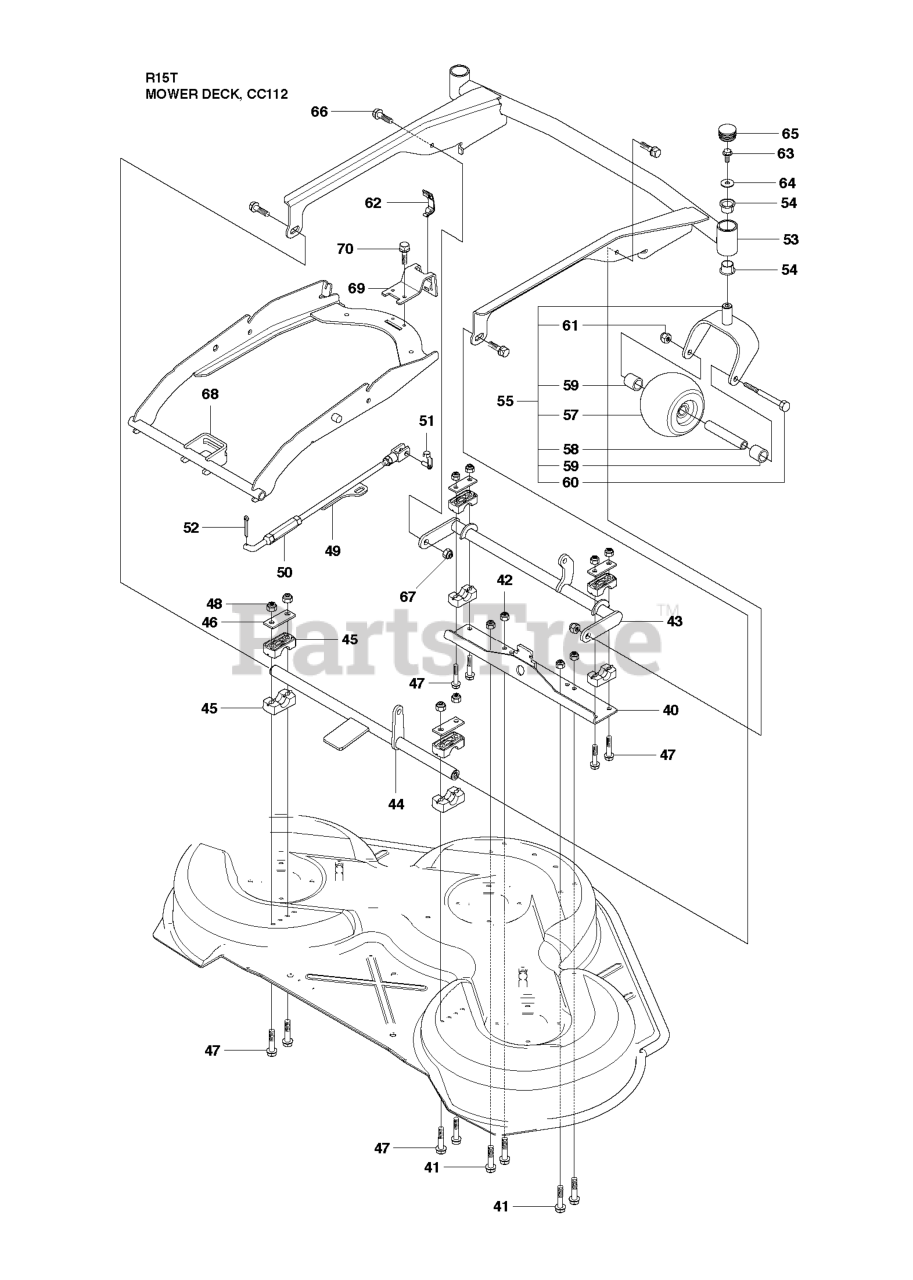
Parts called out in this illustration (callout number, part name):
42	LOCKNUT M8
48	LOCKNUT M8
49	PARALLELL ROD ASSY
50	PARALLEL ROD
51	RETAINER
53	DECK FRAME
55	PIVOT WHEEL ASSY
57	DECK ROLLER, FRONT
61	NUT
62	CLIP GRAY
67	LOCKNUT M8
68	DECK ATTACHMENT
70	SCREW
